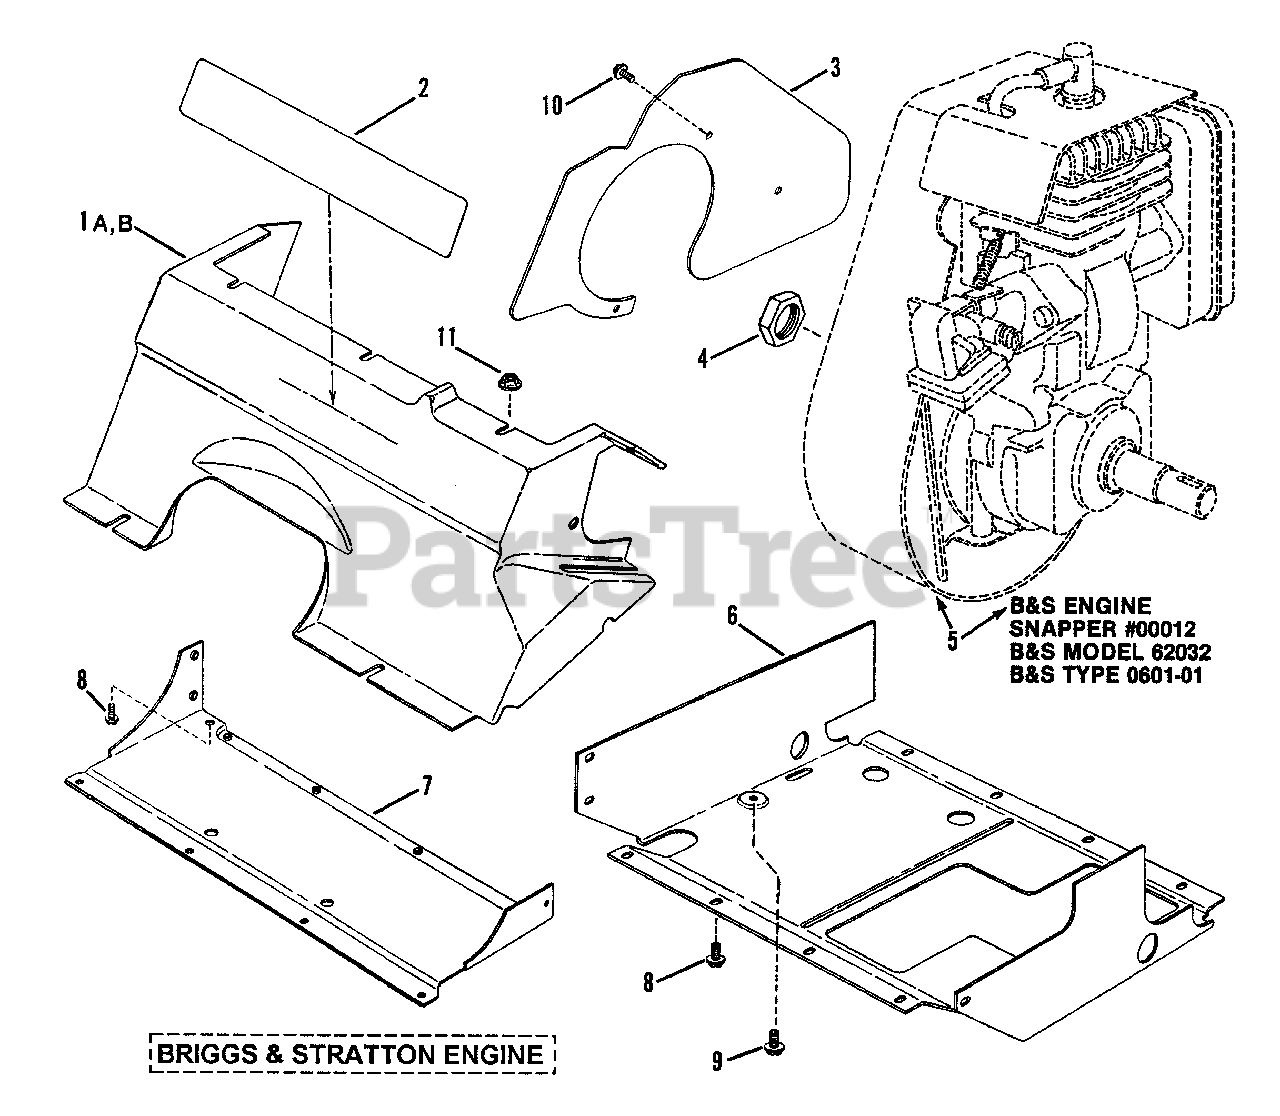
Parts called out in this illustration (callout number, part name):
1A	KIT, Front Cover
1B	COVER, Top
2	DECAL, Snapper
3	PARTITION
4	NUT, 1/4-20 Hex Flange Lock
6	COVER, Bottom
7	BRACE
8	SCREW, #10-24 x 1/4" Hex Washer Self-Tap
9	SCREW, #10-24 x 1/2" Hex Washer Self-Tap
10	SCREW, #8-18 x 1/2" Hex Head Sheet Metal
11	NUT, #10-24 Hex Flange Lock
